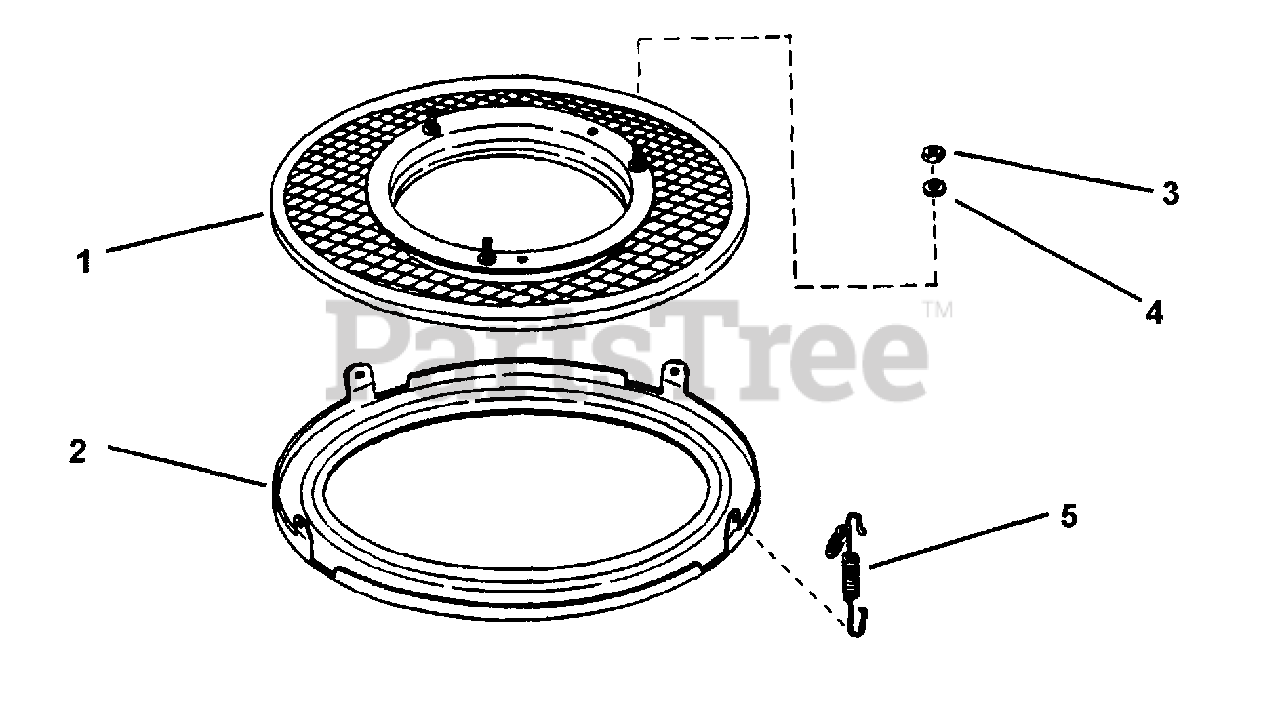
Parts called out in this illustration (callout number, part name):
1	SCREEN, Fastener Assembly
2	RING, Bottom
3	NUT, 5/16-24 Hex, Grade 5
4	WASHER, 5/16 Split Lock
5	SPRING
